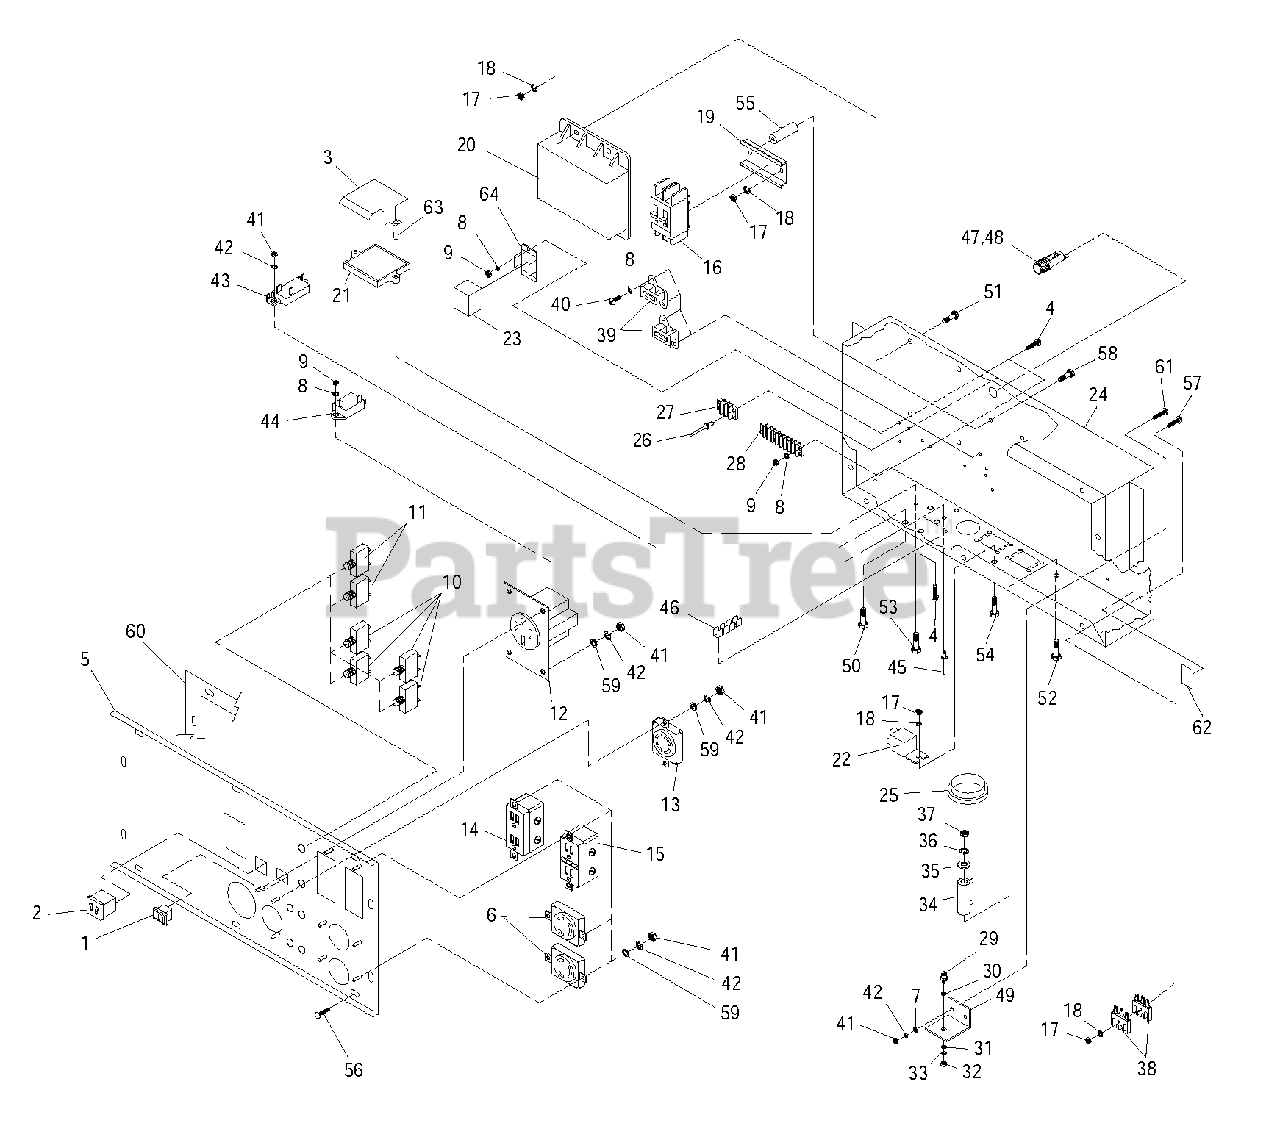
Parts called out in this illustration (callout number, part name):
1	SWITCH, ROCKER -/0
2	OUTLET, 12VDC SNAP
3	COVER, GOVERNOR CONTROL
4	SCREW PPHM M3-0.5 X 12
5	PANEL, SHEET METAL
6	OUTLET 30A 120V RECEPT
7	WASHER FLAT #6
8	WASHER LOCK M3
9	NUT HEX M3-0.5 G8
10	CIRCUIT BREAKER 30A
11	CIRCUIT BREAKER 20A
12	OUTLET 50A 125/250V
13	OUTLET 30A 125/250V
14	OUTLET 20A 120V DPLX
15	OUTLET 20A 120V GFCI
16	CIRCUIT BREAKER 50A 400V 2POLE
17	NUT HEX M5-0.8 G8
18	WASHER LOCK #10
19	DIN RAIL 59.5mm LONG
20	ASSEMBLY VOLTAGE REGULATOR 60HZ
21	ELECTRONIC GOVERNOR / IDLE CONTROLLER
22	RELAY PNL 12VDC SPST 30A
23	RELAY 3PDT 12VDC
24	CONTROL PANEL BOX
25	BUSHING SNAP
26	RIVET POP .156 X .160-.164 / #20
27	BLOCK TERMINAL 20A 2 X 6 X 1100V
28	BLOCK DOUBLE ROW TERMINAL 8 POSITION
29	RECTIFIER MSC 12A 600V
30	WASHER MICA .203
31	WASHER STEP NYLON .20
32	NUT HEX #10-32
33	WASHER FLAT #10
34	RESISTOR 25R 5% 25W
35	WASHER FLAT 1/4
36	WASHER LOCK M6-1/4
37	NUT HEX M6-1.0 G8
38	RECTIFIER-BATTERY CHARGER
39	TRANSFORMER, IDLE CURRENT
40	SCREW PPHM M3-0.5 X 8
41	NUT HEX M4-0.7 G8
42	WASHER LOCK M4
43	CIRCUIT BREAKER 6 X 1
44	CIRCUIT BREAKER 10 X 1 12VDC 1/4"QC
45	RIVET POP .125 X .129-.133 / #30
46	LUG GRND 8 TABS
47	HOLDER FUSE
48	FUSE 10A X AGC10
49	HEATSINK
50	SCREW PPHM M4-0.7 X 10
51	SCREW HHC M5-0.8 X 16 G8.8
52	SCREW HHC M6-1.0 X 65 G8.8
53	SCREW HHC M5-0.8 X 25 G8.8
54	SCREW HHC M5-0.8 X 10 G8.8
55	SPACER .25 X .50 X 1.5
56	SCREW HHTT M5-0.8 X 10
57	SCREW PPHM M5-0.8 X 30
58	SCREW PPHM M5-0.8 X 50
59	WASHER FLAT #8
60	GASKET, PORTABLE CONTROL PANEL
61	SCREW PPHM M4-0.7 X 16
62	TAPE ELEC UL PERMACEL
63	NUT TRIC M5-0.8
64	RELAY BASE 3PDT 12VDC
